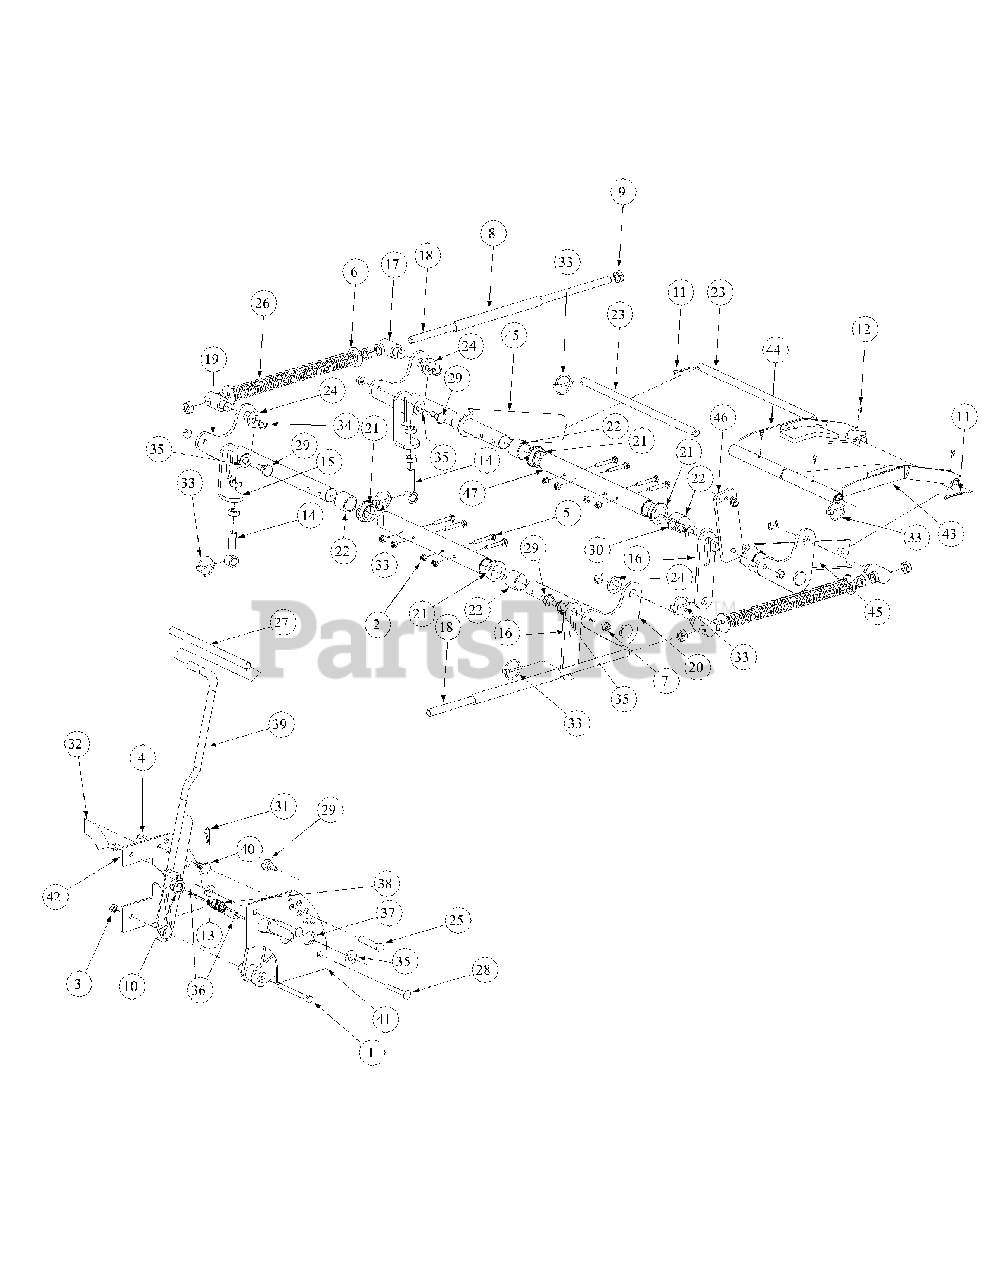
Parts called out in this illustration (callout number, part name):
1	Hex Cap Screw, 3/8-16, 3.75
2	Nut, 5/16-18, Nylock
3	Nylock Insert Lock Nut, 3/8-16
4	Nylock Insert Lock Nut, 1/2-13
5	Hex Cap Screw, 5/16-18 x 2
6	Flat Washer, 5/8
7	Hex Nut, Flange Lock, 3/8-16
8	Hose, 5/8 ID 13/16 OD, 8" LG
9	Jam Nut, 5/8-11
10	Flat Washer, .06, .776, 1.25
11	Cotter Pin, 3/16 x 1-1
12	Grease Fitting, 1/4-28 x 3/16
13	Idler Washer
14	Eye Bolt, 5/8ID
15	Eye Bolt Mount Link, 5/8 ID
16	Deck Link
17	Ferule Lift
18	Lift Connector Rod
19	Bellecrank Weldment Lift, Left Hand
20	Bellecrank Weldment Lift, Right Hand
21	Hex Flange Bearing, 1.25 ID
22	Frame Lift Spacer
23	Front Lift Link, Rod Mount
24	Spacer, .812 ID x .268 Lg.
25	Clevis Pin, .500 Dia. x 2.625 Lg.
26	Lift Compression Spring
27	Lift Handle Grip
28	Carriage Bolt, 3/8-16, 2.75
29	Shoulder Screw, 0.625 OD x .437 Lg.
30	Shoulder Screw, 0.625 OD x .830 Lg.
31	Cotter Pin, .148 x 3.00
32	Decal Height Indicator
33	Linch Pin, 3/16 Dia.
34	E Clip, 3/4 Dia.
35	Nylon Flat Washer, 5/8
36	Spacer, .39 ID x .63 OD x 1.442
37	Lift Pivot Assembly
38	Lift Handle Spring
39	Lift Handle Assembly
40	Shoulder Screw, 5/8 OD x 0.264
41	Outer Lift Index Plate
42	Inner Lift Index Plate
43	Bearing Lift Brace Assembly, Right Hand
44	Bearing Lift Brace Assembly, Left Hand
45	Front Frame Strut Assembly
46	Lift Link Adjustment
47	Lift Shaft Holder
